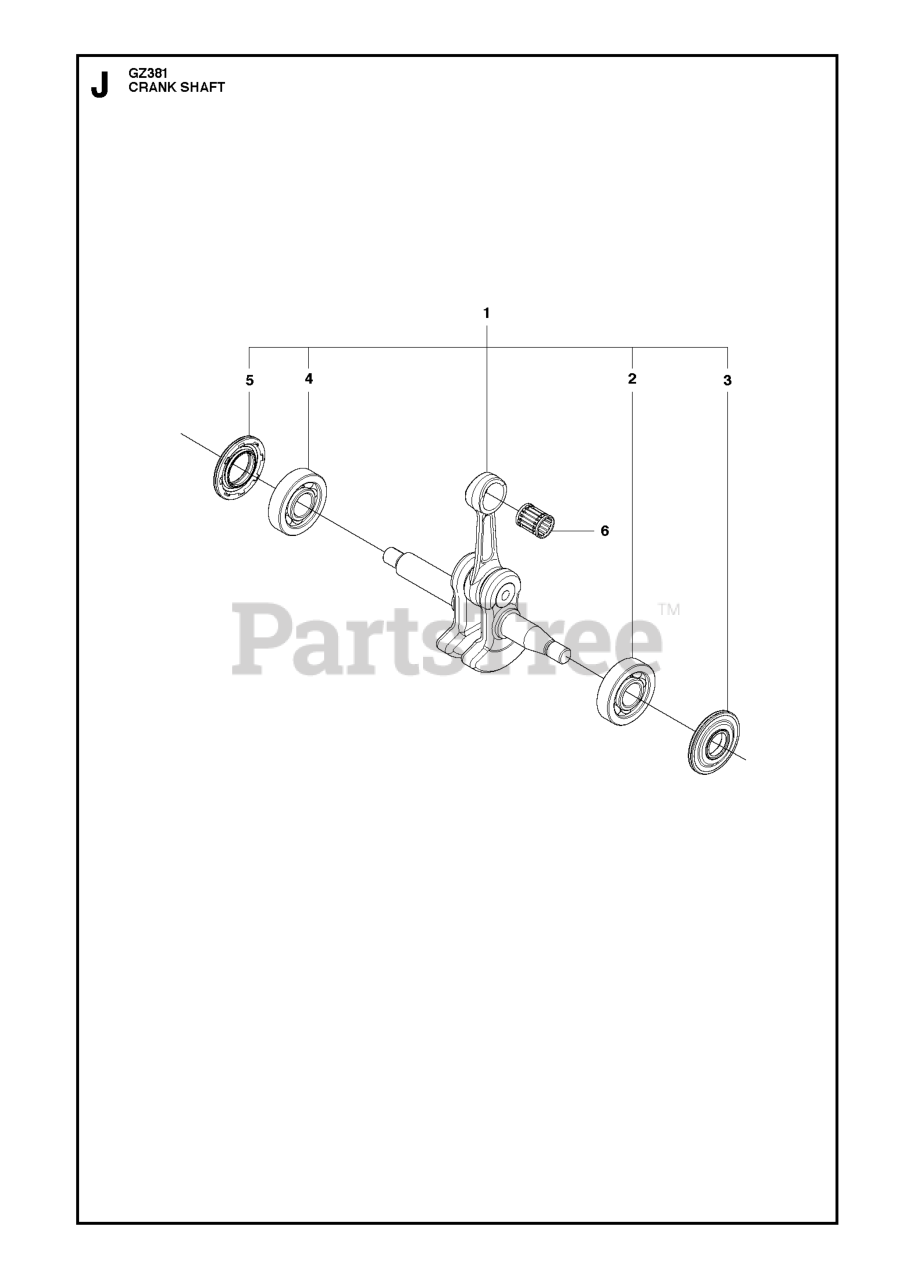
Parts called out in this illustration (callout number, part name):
1	CRANKSHAFT & GEAR ASSY
2	BALL BEARING
4	BALL BEARING
6	SUPPORT BUSHING
